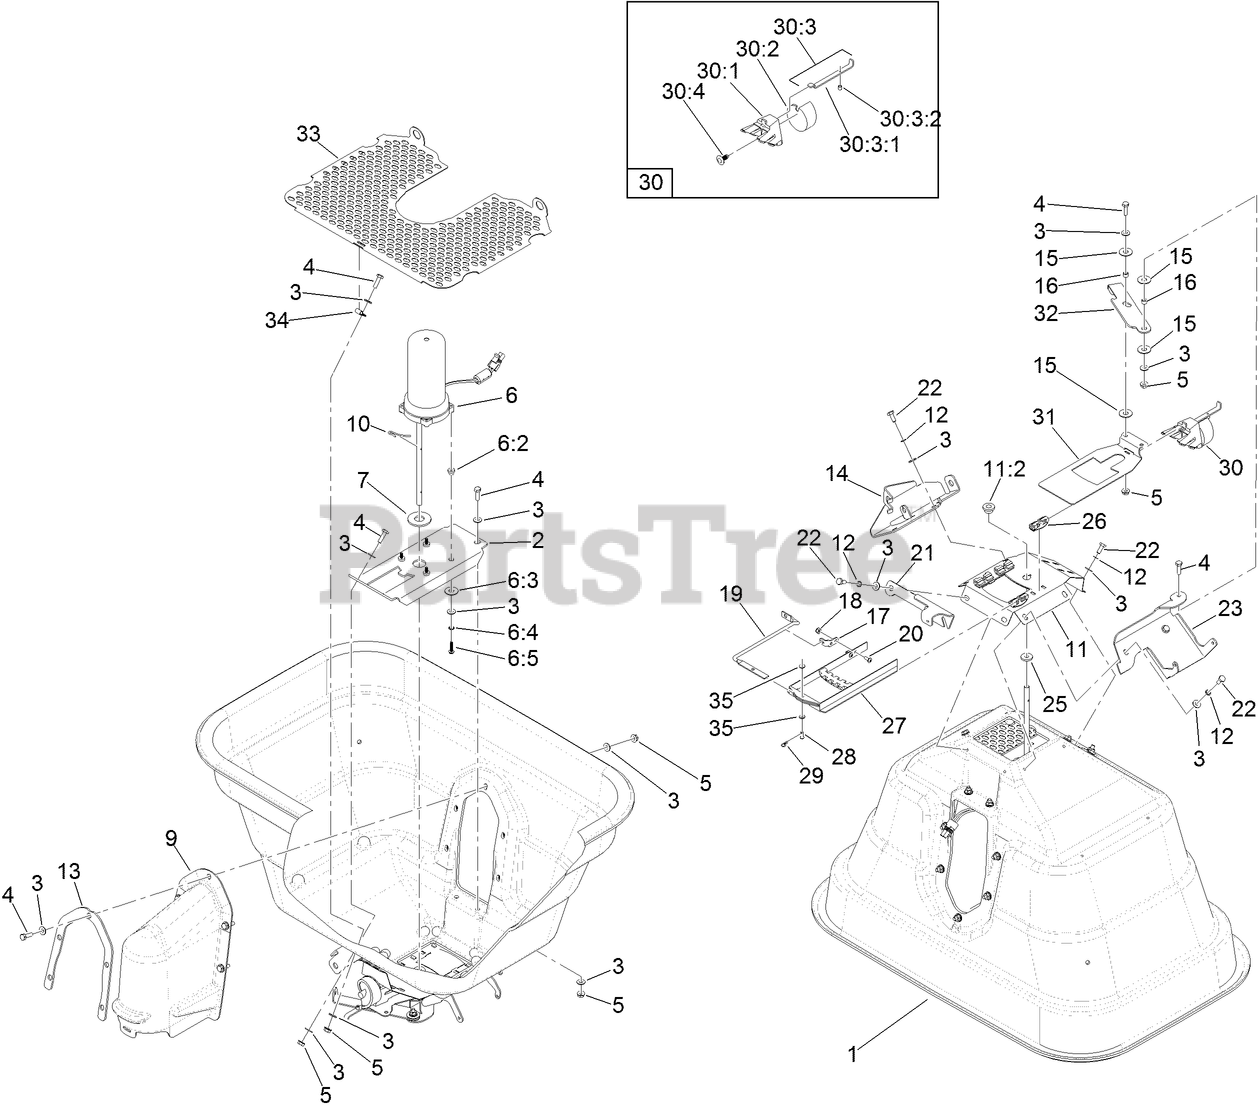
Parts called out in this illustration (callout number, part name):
1	HOPPER-SPREADER, 175 LB
2	BRACKET-MOUNT, MOTOR
3	WASHER-FLAT
4	SCREW-HH
5	NUT-HF
6	SPREADER MOTOR ASM
6:2	SPACER-FLANGED
6:3	WASHER-FLAT
6:4	WASHER-LOCK, INT
6:5	SCREW-SHWH
7	SPACER
9	COVER-MOTOR
10	AGITATOR
11	MULCH PLATE W/ BEARING ASM
11:2	BEARING-BOTTOM, HOPPER
12	WASHER-LOCK, INT
13	FLANGE-COVER, MOTOR
14	BRACKET-HOPPER, GATE CONTROLS
15	WASHER
16	SPACER
17	BRACKET-DIFFUSER
18	NUT-HEX
19	ROD-CONTROL, DIFFUSER
20	SCREW-PPH
21	BRACKET-SPRING, HOPPER DEFLECTOR
22	SCREW-HH
23	BRACKET-LEVER, HOPPER GATE
25	WASHER-FELT
26	GUIDE-RATE, GATE
27	DIFFUSER
28	PIN-CLEVIS
29	PIN-COTTER, HAIR
30	RATE DIAL ASM
30:1	MOUNT-DIAL
30:2	DIAL
30:3	RATE GATE LINK ASM
30:3:1	LINK-GATE, RATE
30:3:2	SCREW-SHOULDER, SLOTTED
30:4	CLIP
31	GATE-RATE
32	LEVER-GATE
33	SCREEN-HOPPER, SMALL HOLE
33	SCREEN-HOPPER, MEDIUM HOLE
33	SCREEN-HOPPER, LARGE HOLE
34	CLAMP-LOOP
35	WASHER-FLAT
